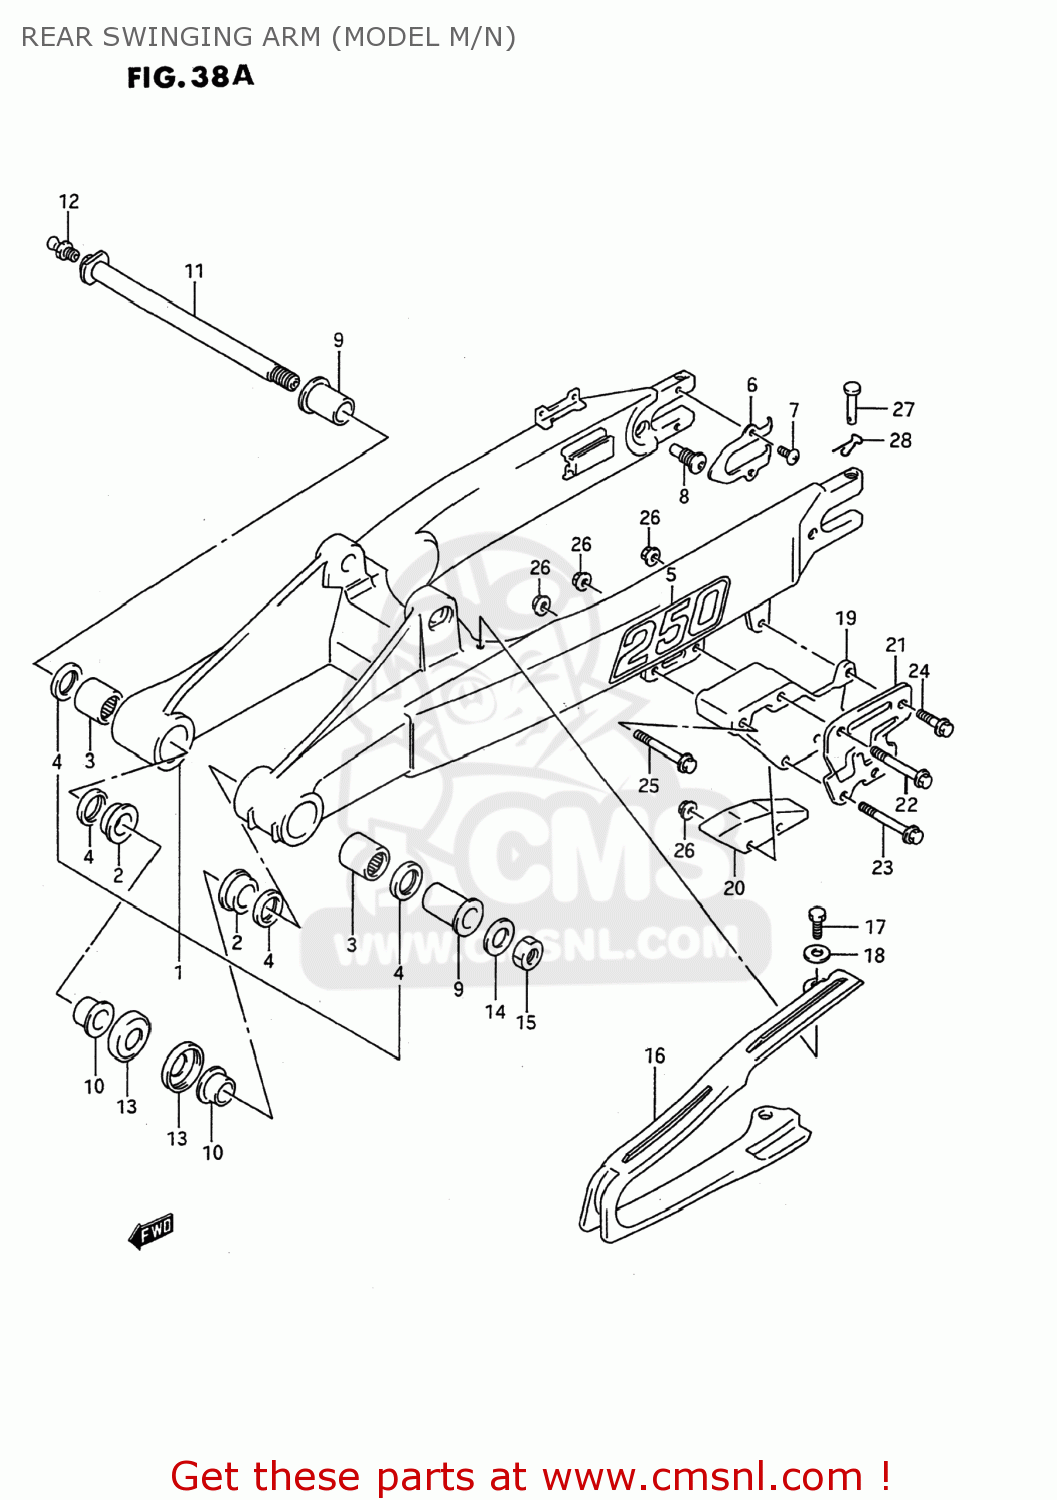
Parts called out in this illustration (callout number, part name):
1	SWING ARM ASSEMBLY,REAR
2	BUSHING,SWGARM PIVOT
3	BEARING(22X29X30)
4	SEAL,OIL(22X29X4)
5	EMBLEM,SWINGINGARM
6	PLATE,SWING ARM,REAR
7	SCREW (5X8)
8	SCREW (M10X21)
9	SPACER,RR SWGARM PIVOT
10	SPACER,SWGARM PIVOT INNER
11	SHAFT COMP,SWING ARM PIVOT
12	NIPPLE
13	COVER,SWINGINGARM PIVOT
14	WASHER
15	NUT
16	BUFFER,CHAIN TOUCH DEFENSE
17	BOLT
18	WASHER
19	GUIDE,CHAIN
20	DEFENSE,CHAIN GUIDE
21	PLATE,CHAIN GUIDE OUTER
22	BOLT
23	BOLT
24	BOLT
25	BOLT
26	NUT
27	PIN
28	CLIP
